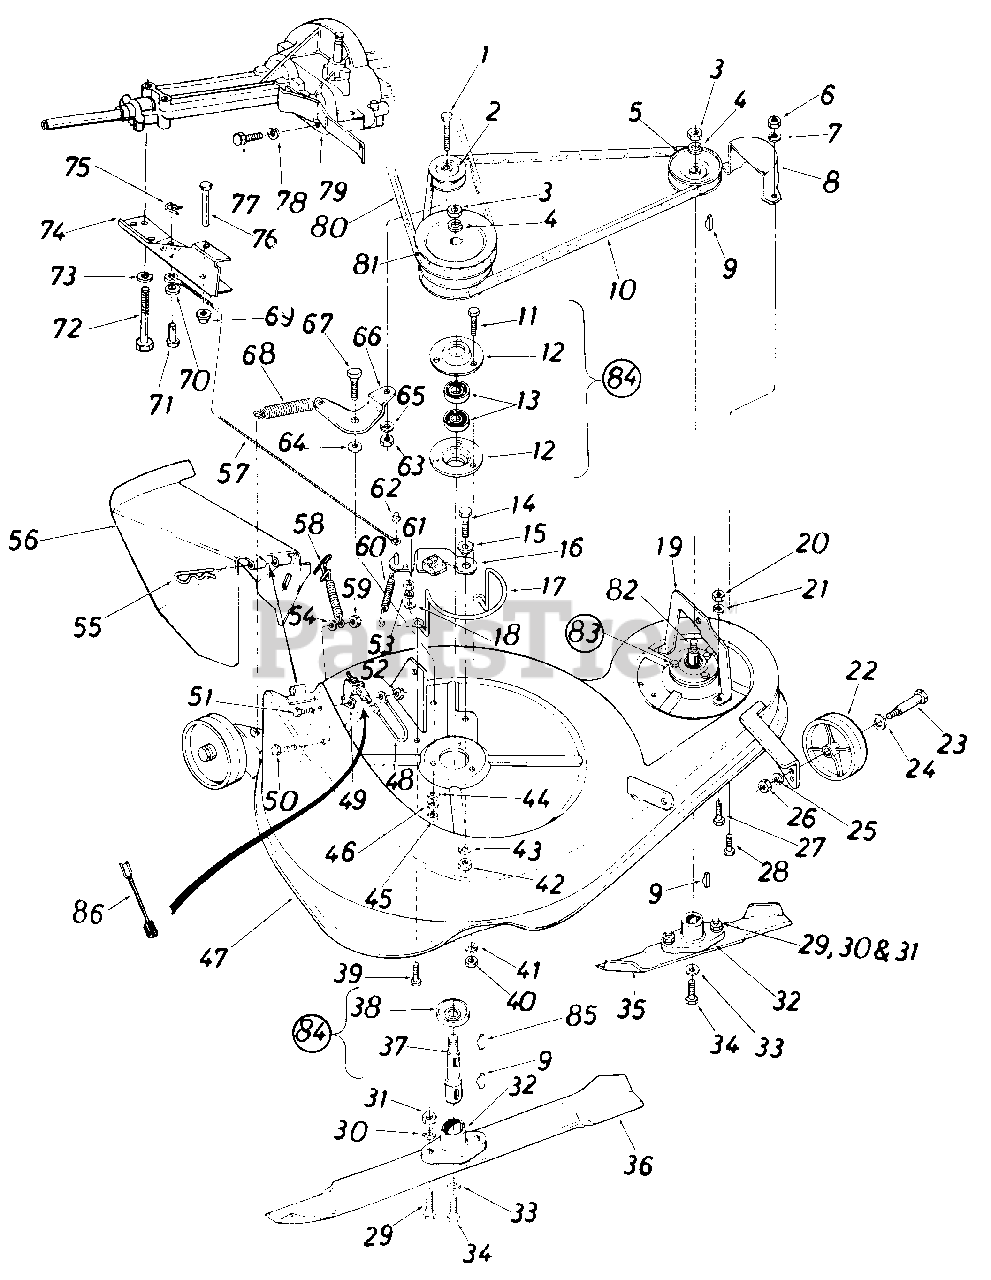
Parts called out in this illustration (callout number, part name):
1	Hex Bolt 3/8-24 x 1.50" Lg.
2	"V"-Idler Pulley 3.06" O.D.
3	Hex Jam Nut 5/8-18 Thd.
4	Bell-Wash. .630" I.D. x 1.25 x .090
5	Pulley 3.56" O.D. x 5/8
6	Hex Nut 1/4-20 Thd.
7	L-Wash. 1/4" I.D.
8	Belt Guard Cover
9	#6 Hi-Pro Key 5/32 x 5/8" Dia.
10	V-Belt 1/2 x 53" Lg. (4L)
11	1 Hex Bolt 5/16-18 x .75" Lg.
12	Brg. Housing 1.85" I.D.
13	Ball Bearing .787" I.D. x 1.85" O.D.
14	Hex Bolt 5/16-18 x 1.0" Lg. (Grade 5)
15	Shld. Spacer .500" Dia. x .27" Lg.
16	Blade Brake Brkt. Ass'y.
17	Belt Guard
18	Fl-Wash. .344" I.D. x .875" O.D.
19	Deck Bracket
20	Hex Nut 5/16-18 Thd.
21	L-Wash. 5/16 I.D.
22	Deck Wheel 5.0" x 1.38"
23	Shoulder Bolt .498" Dia. x 1 .635
24	Belleville .400" I.D. x .88" 0. D.
25	L-Wash. 3/8" I.D.
26	Hex Nut 3/8-16 Thd.
27	Hex Bolt 5/16-18 x .75" Lg.
28	Hex Bolt 1/4-20 x .62" Lg.
29	Hex Bolt 5/16-24 x 1.00" Lg. (Grade 5)
30	L-Wash. 5/16" I.D.
31	Hex Nut 5/16-24 Thd.
32	Blade Adapter
33	L-Wash. 3/8" I.D. H.D.
34	Hex Bolt 3/8-24 x 1.50" Lg. (Grade 5)
35	13" Blade
36	24" Blade
37	Blade Spindle (4.90" Lg.)
38	Bearing Shield
39	Hex Bolt 5/16-18 x .75" Lg.
40	Hex Nut 5/16-18 Thd.
41	L-Wash. 5/16" I.D.
42	Hex Nut 5/16-18 Thd.
43	L-Wash. 5/16" I.D.
44	Hex Nut 5/16-18 Thd.
45	Hex Nut 5/16-18 Thd.
46	L-Wash. 5/16" I.D.
47	36" Deck Ass'y.
48	Ground Wire
49	Safety Switch
50	Truss Mach. Scr. 1/4-20 x .50" Lg.
51	Hex Bolt 1/4-20 x .62" Lg.
52	Hex Nut 1/4-20 Thd.
53	L-Wash. 5/16" I.D.
54	Fl-Wash. .281" I.D. x .50" 0. D.
55	Internal Cotter Pin
56	Chute Deflector
57	Brake Cable Ass'y.
58	Spring Latch Ass'y.
59	Hex Nut 1/4-20 Thd.
60	Extension Spring .38" O.D. x 3.25" Lg.
61	Hex Nut 5/16-18 Thd.
62	Cap Speed Nut 1/4" Rod
63	Hex Nut 3/8-16 Thd.
64	Fl-Wash. .344" I.D. x .875" 0. D.
65	L-Wash. 3/8" I.D.
66	Deck Idler Brkt. Ass'y.
67	Shoulder Bolt .498" Dia. x .71 0
68	Extension Spring
69	Cap Speed Nut 1/4" Rod
70	Fl-Wash. .281" I.D. x .50" 0. D.
71	Clevis Pin '/4" Dia. x .53" Lg.
72	Hex Bolt 5/16-18 x 2.75" Lg.
73	L-Wash. 5/16" I.D.
74	Lower Outside Belt Guard
75	Intern. Cot-Pin 5/16" Dia.
76	Weld Pin .25" Dia. x 2.5" Lg.
77	Hex Bolt 1/4-20 x .62" Lg.
78	L-Wash. 1/4" I.D.
79	Lower Inside Belt Guard
80	V-Belt 1/2 X 50" Lg.
81	Pulley 5.81" O.D. x 5/8
82	Blade Spindle (3.70" Lg.)
83	Spindle Ass'y.
84	Spindle Ass'y.
85	#61 Hi-Pro Key 3/16" x 518" Dia.
86	Wire Lead
